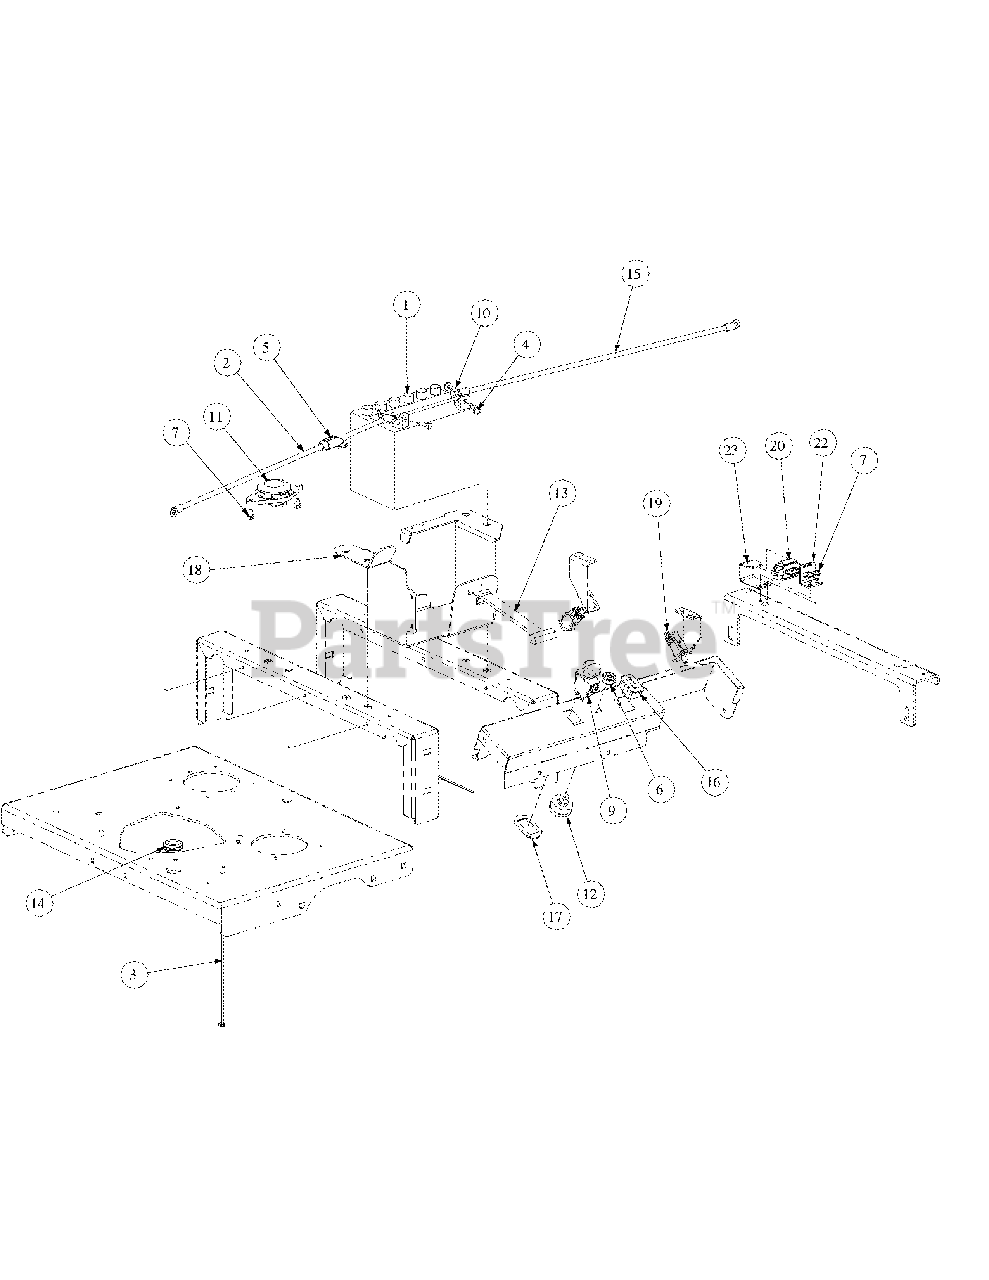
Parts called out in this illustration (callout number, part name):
2	Cable, Battery, Red, 36"
3	Tie, Cable, 3/16 x .05 x 7.4"
4	Screw, Hex, Cap, 1/4-20 x .75
5	Boot, 1" OD Rubber Battery-PST, Red
6	Nut, W/Cap, 5/8-32 Ignition
7	Screw, TT, 1/4-20 x .500, Hex Index Washer
8	Hourmeter, Harness
9	Switch, Electric, PTO
10	Nut, 1/4-20, Hex Flange Lock Nut
11	Switch, Seat N/C
12	Switch, Ignition, 6 Pin
13	Strap, Battery
14	Grommet, .75 ID
15	Cable, Battery Black, 24"
16	Meter, Hour
17	Bracket, PTO Switch Retainer
18	Mount Bracket, Battery
19	Switch, Safety
20	Switch, Plunger
21	Harness Assembly, kohler
22	Switch Bracket Mount
23	Switch Clamp
